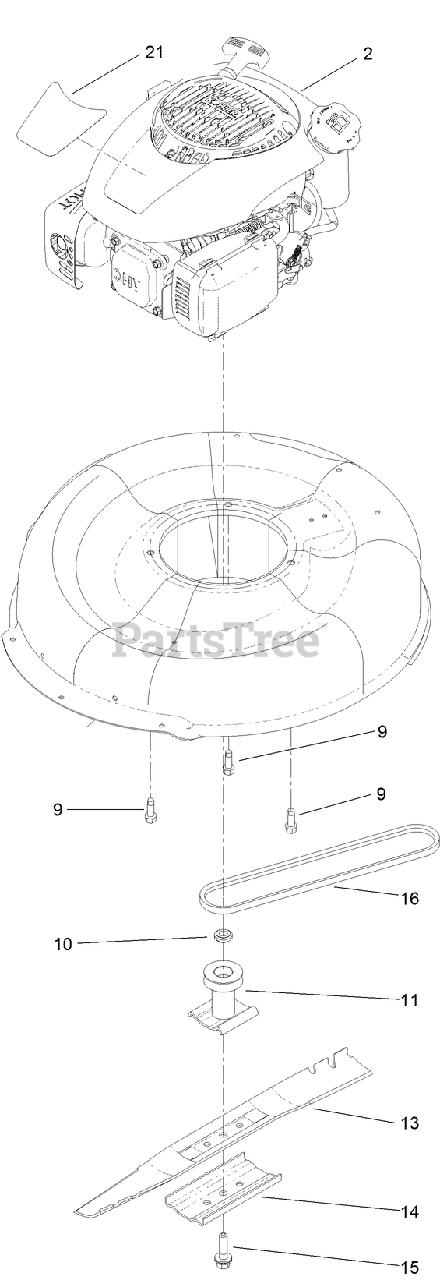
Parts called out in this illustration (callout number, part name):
9	SCREW-TAPTITE
10	SPACER-DRIVER
11	DRIVER-BLADE
14	SUPPORT-BLADE
15	BOLT-BLADE
